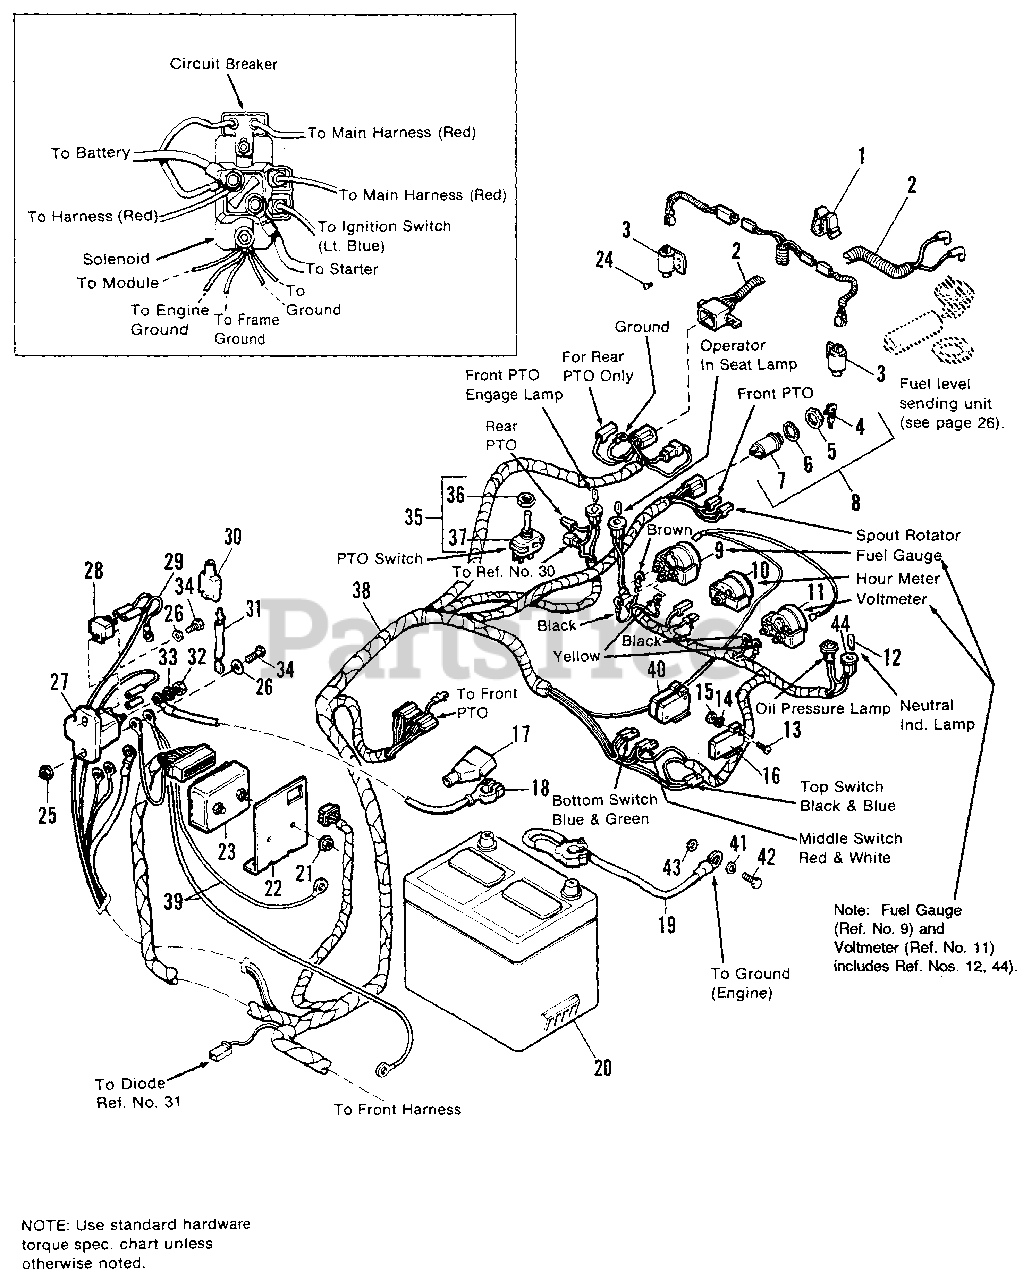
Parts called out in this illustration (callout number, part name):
1	CLIP, Tinnerman
2	HARNESS, Rear
3	SAFETY SWITCH (Seat), Operator Present
5	NUT, Special
8	SWITCH & KEY ASSY., Ignition
9	GAUGE, Fuel
13	SCREW, R.H., #5-24 x 1-1/2
14	LOCKWASHER, #5
15	NUT, Hex, #5-24
16	SWITCH, Interlock (Under Dash) Shift Lever
17	PROTECTOR, Battery (Red)
18	CABLE (Battery to Solenoid)
19	CABLE (Battery to Ground)
20	BATTERY (491 AMP Cold Crank Rating)
21	NUT, w/Washer, #8-32
22	BRACKET, Interlock, Mod.
23	INTERLOCK MODULE
24	SCREW, Tap, #10-32
25	NUT, Hex, Flange, Whizlock 1/4-20
26	WASHER, Plain, 1/4
27	SOLENOID (12 Volt DC)
28	BREAKER, Circuit
29	WIRE ASSY. (Circuit Breaker to Solenoid)
30	CONNECTOR, 3 Way
31	WIRE ASSY., Diode
32	NUT, Hex, Jam, 5/16-24
33	LOCKWASHER, 5/16, Pltd.
34	CAPSCREW, Hex Hd., 1/4-20 x 3/4
35	SWITCH ASSY., PTO (incl. Ref. Nos. 36 & 37)
36	NUT, Special
38	WIRING HARNESS (Main)
39	WIRE ASSY., Harness to Engine Ground
40	DUAL INTERLOCK SWITCH
41	LOCKWASHER, 1/4
42	CAPSCREW, Hex, Ext., 1/4-20 x 5/8
43	LOCKWASHER, Ext., 1/4, Zinc Pltd.
44	BULB HOLDER
